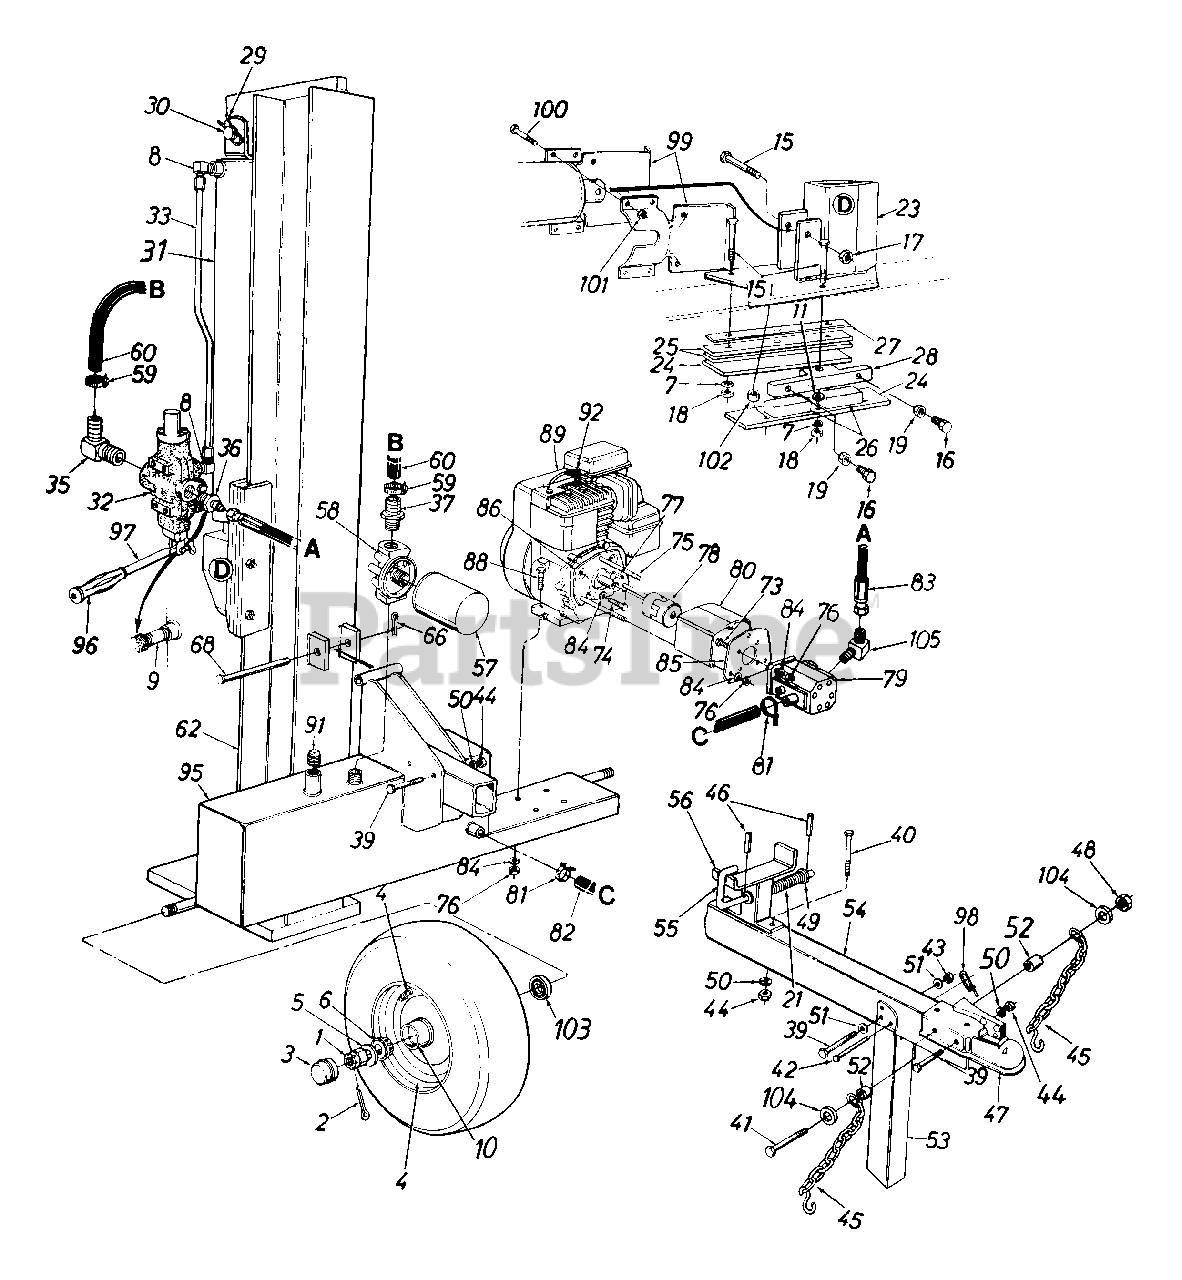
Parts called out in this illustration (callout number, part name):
1	Slotted Nut 3/4-16 Thd.
2	Cotter Pin 5/32" Dia. x 1-1/4" Lg.
3	Hub Cap
5	Fl-Wash. .76" I.D. x 1.5" O.D.
6	Bearing Cone
7	L-Wash. 1/2" I.D.
8	90ø Solid Male Adapter
9	Pipe Nipple 1/2 NPT
10	Bearing Cup
11	Fl-Wash. .531" I.D. x .94" O.D.
15	Hex Bolt 1/2-20 x 2.75" Lg. (Grade 8)
16	Hex Bolt 3/8-24 x 1.5" Lg.
17	Hex L-Nut 1/2-20 Thd.
18	Hex Nut 1/2-20 Thd.
19	Hex Jam Nut 3/8-24 Thd. (Grade 5)
21	Comp. Spring 4" Lg.
29	External Cotter Pin
30	Cylinder Mounting Pin
33	Metal Pressure Tube
35	Return Elbow
36	Adapter
37	3/4" Hose Barb.
39	Hex Bolt 3/8-16 x 2.75" Lg. (Grade 8)
40	Hex Bolt 3/8-16 x 4" Lg.
41	Hex Bolt 3/8-16 x 4" Lg. (Grade 5)
42	Clevis Pin 5/16 x 2.5" Lg.
43	Hex L-Nut 3/8-16 Thd.
44	Hex Nut 3/8-16 Thd.
45	Chain - Tow Hitch
46	Roll Pin
47	Hitch Coupler
48	Hex Ctr. L-Nut 3/8-16 Thd.
49	Fl-Wash. .635" I.D. x .93" O.D.
50	L-Wash. 3/8" I.D.
51	Fl-Wash. .406" I.D. x .75" O.D.
52	Spacer 3/8" I.D. x .625" O.D.
55	Locking Rod
57	Fllter Element
58	Fllter Head
59	Hose Clamp 5/8"
60	Return Hose 3/4" I.D. x 44" Lg.
68	Hinge Pin 1/2 x 4.8" Lg.
73	Hex Bolt 5/16-24 x 1" Lg.
74	Hex Bolt 5/16-24 x .62" Lg.
75	Hex Bolt 5/16-24 x 4" Lg.
76	Hex Nut 5/16-24 Thd.
77	Sq.-Key 3/16" x .75"
78	Flexible Coupling
79	Gear Pump
80	Coupling Shield
81	Hose Clamp
82	Suction Hose
83	High Pressure Hydraulic Hose
84	L-Wash. 5/16" I.D.
88	Hex Bolt 5/16-24 x 1.75" Lg.
89	Engine
91	L-Vent Pipe Plug
92	Spark Plug Boot
95	Tank Ass'y.
96	Grip
97	Control Handle
98	Spring Pin
101	Hex L-Nut 3/8-16 Thd.
102	Spacer 1/2" I.D. x .68" Lg.
103	Bearing Seal Only
104	Fl-Wash. 3/8" I.D. x .87" O.D.
105	90ø Male Adapter
